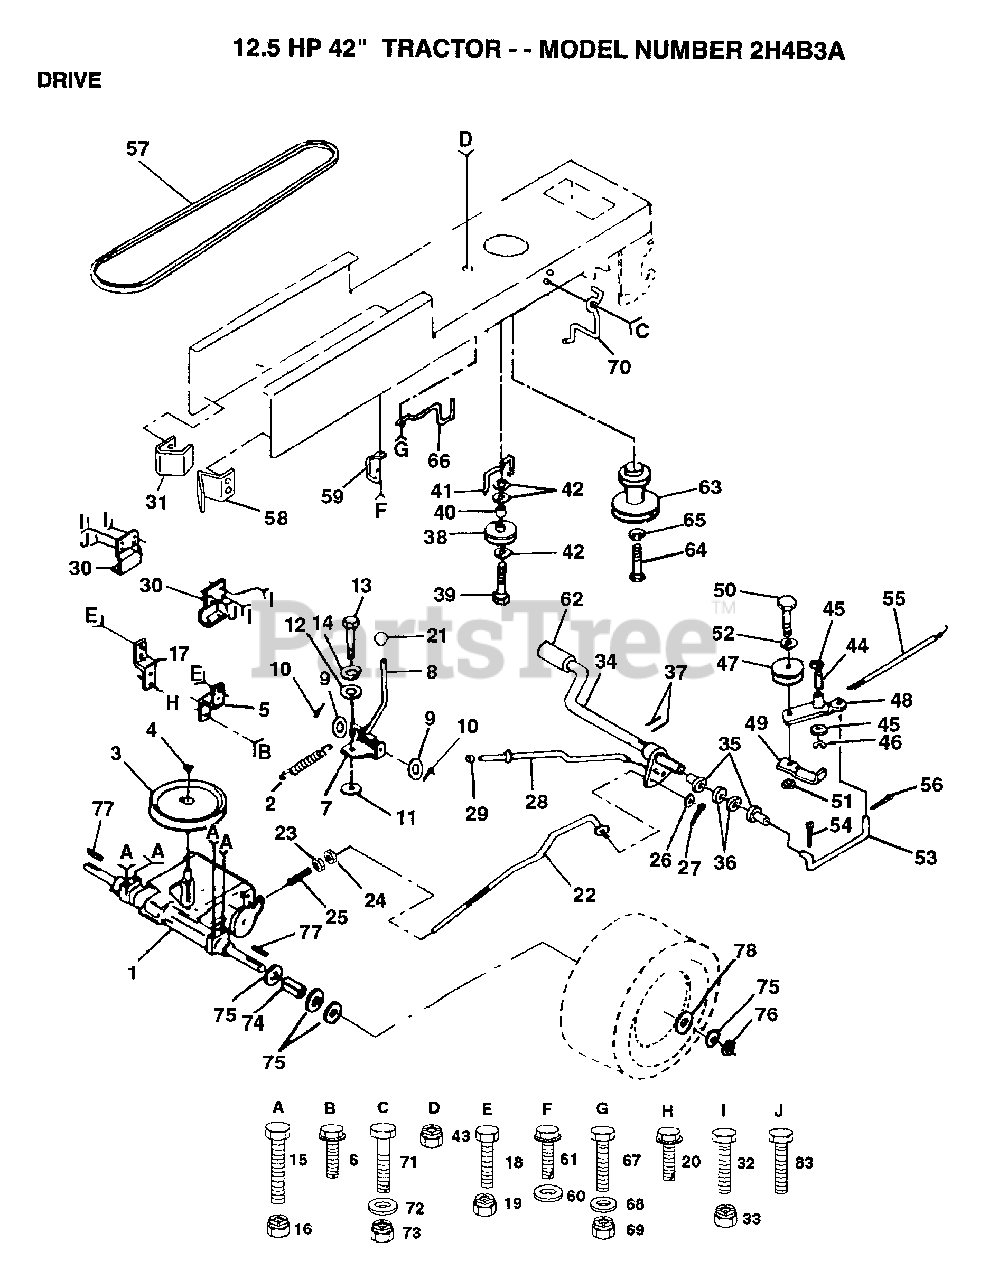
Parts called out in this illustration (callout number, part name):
3	PULLEY TRANS
5	STRAP TORQUE
6	SCREW
8	SHIFT ROD
9	WASHER
10	PIN COTTER 1/8
11	WASH-SHFT PLT LT
12	WASHER LT
14	LOCKWASHER
15	BOLT
17	STRAP TORQUE
20	SCREW
21	KNOB T (1/2-HOLE)
22	BRAKE ROD
23	NUT
24	NUT
25	SPRING ROD LT
26	WASHER
27	COTTER PIN
28	PARKING BRAKE ROD
29	PLUNGER CAP T
30	TRANSAXLE MTG BKT
31	"KEEPER,BELT LH T"
32	BOLT
35	NYLON BEARING
36	WASHER LT
38	PULLEY.IDLER.FLAT
39	BOLT
40	SPACER T
41	BELT KEEPER LT
42	WASHER
44	"LY, BEARING"
45	WASHER LT
46	KLIP RING
48	ARM IDLER
49	RETAIN BELT
52	WASHER
53	"LINK, CLUTCH T"
54	COTTER PIN
55	"SPRING, RETURN LT"
56	COTTER PIN
57	BELT.V.GDRIVE.95
58	"KEEPER,BELT RH T"
60	WASHER
61	SCREW
62	PEDAL COVER T
64	BOLT
65	LOCKWASHER
66	KEEPER.BELT.ENG.L
67	BOLT
68	WASHER
70	KEEPER BELT ENG
71	BOLT
72	WASHER
74	SPACER LT
75	WASHER
76	E-RING LT
77	SQUARE KEY
78	WASHER
83	SCREW
